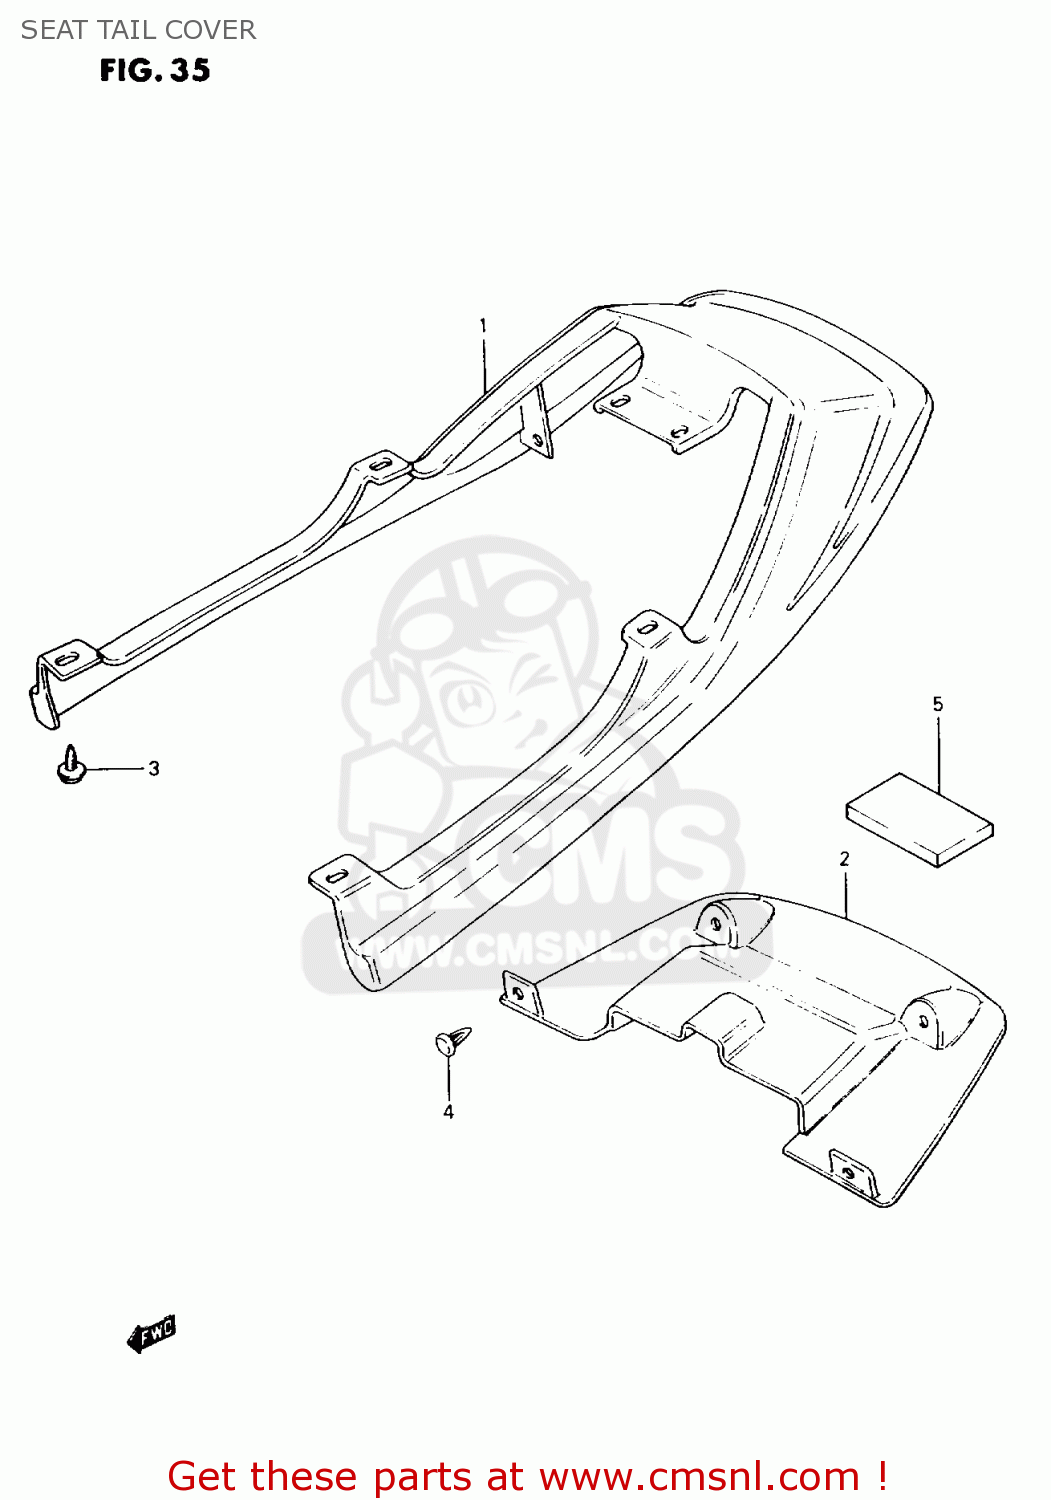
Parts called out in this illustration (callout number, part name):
1	COVER, SEAT TAIL (RED)
2	LID,TAIL COVER SEAT
3	SCREW
4	CLIP
5	CUSHION
